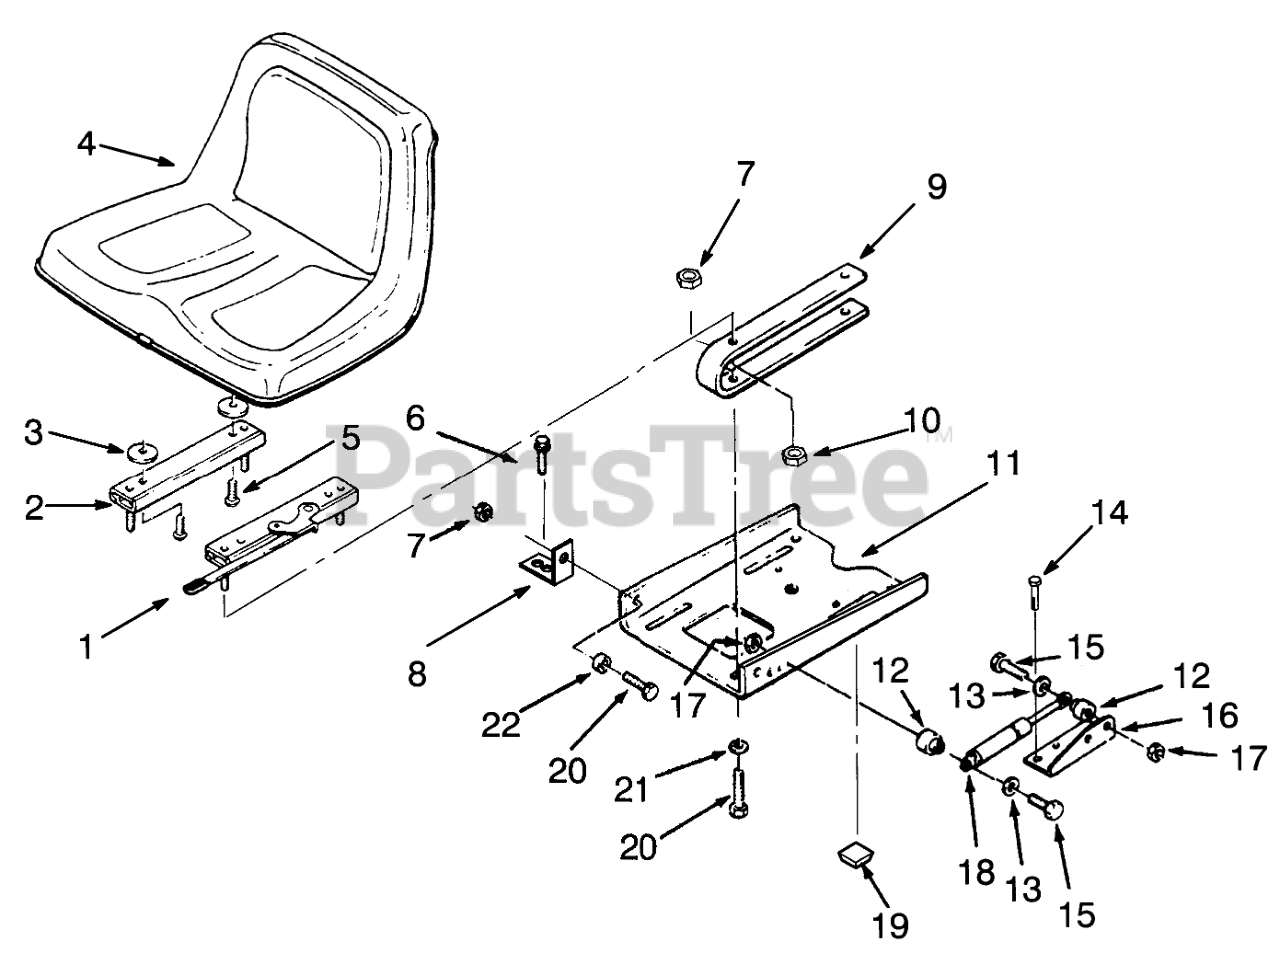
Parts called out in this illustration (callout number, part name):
1	Adjuster-Seat
2	ADJUSTER-R.H. SEAT
3	SPACER-NYLON
4	Seat
6	Bolt
7	NUT-LOCK, NI
8	BRACKET-PIVOT
9	Seat Spring
10	Nut
11	Plate-SeatPivot
12	SPACER
13	WASHER-FLAT
14	Bolt
15	SCREW-HH
16	BRACKET-CYLINDER R
17	NUT-LOCK, NI
18	GAS SPRING
19	BUMPER SJ5514 BLACK
20	SCREW-HH
21	WASHER-PLAIN
22	BUSHING
